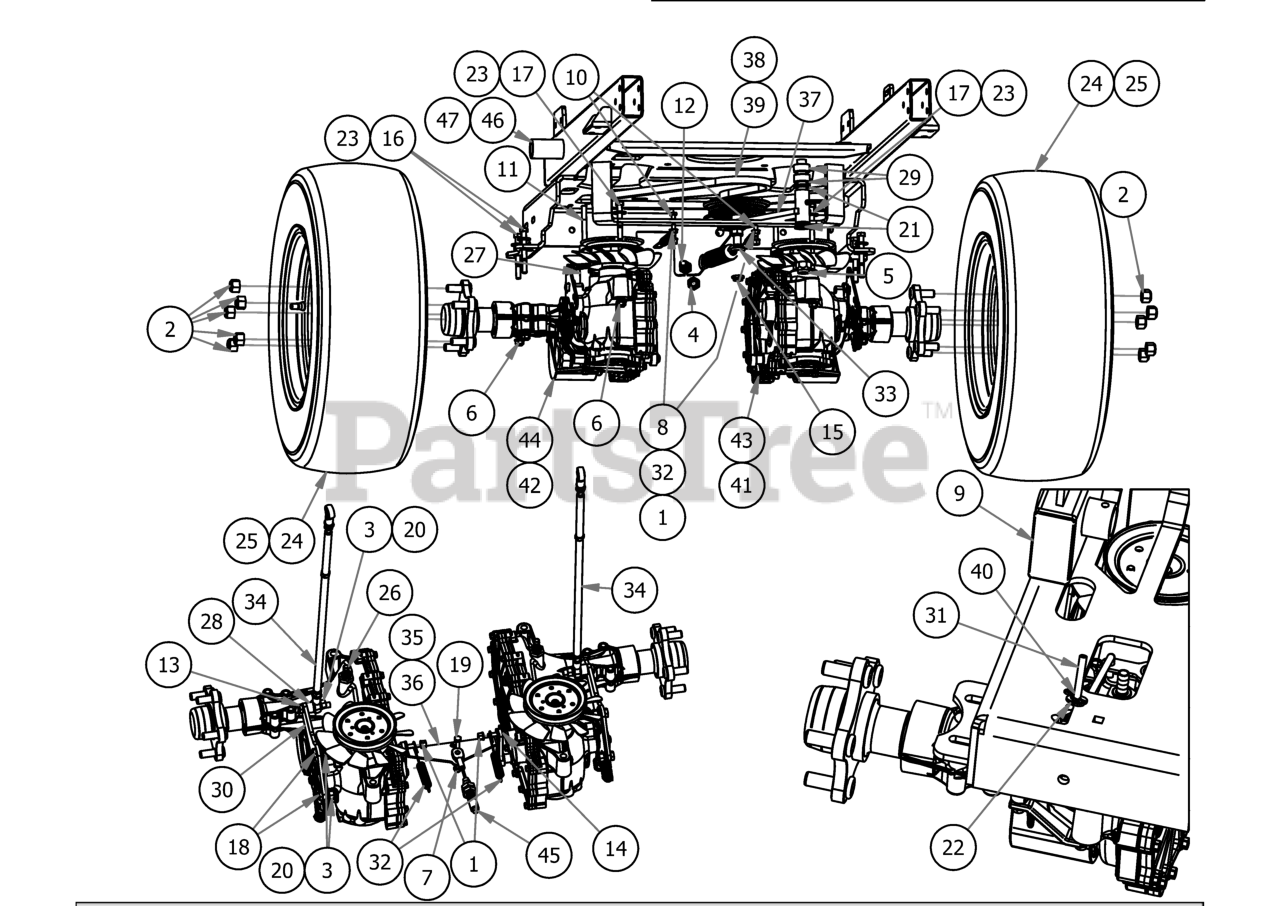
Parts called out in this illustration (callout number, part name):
1	1/4-20 Nylon Insert Flange Nut
2	Acorn Lug Nut
3	3/8" Hex Nut
4	1/2-13 Hex Nuts Zinc
5	5/8-11 NYLON INSERT LOCKNUT ZINC (NOT ON 36)
6	5/16-18 Nylon Flange Nut
7	1/4" Nylock Nut
8	1/4-20 Hex Flange Nuts Zinc w/Serrations
9	1 1/2 x 3 Frame Plug
10	1/4-20 x 2 Hex Bolt
11	5/16x6 Carriage Bolt-Grade 5
12	All Thread-Pump Idler Tensioner
13	3/8"-16 x 2" Gr 5 Hex Bolt
14	1/4-20 x 1 GR 5 hex bolt zinc
15	1/2-13 NYLON INSERT JAM LOCKNUT ZINC
16	5/16" x 3" Hex Bolt
17	5/16" x 2 1/2" Bolt
18	3/8-16 X 1 GR 5 Hex Bolts Zinc
19	1/4" x 3/4" Hex Bolt
20	3/8" Lock Washer
21	.630 ID Plastic Washer (NOT ON 36)
22	1/4 USS FLAT WASHER (3/4 OD) ZINC
23	5/16 USS FLAT WASHER (7/8 OD) ZINC
24	23x9-12 Reaper Turf Tire & Wheel Assembly
25	21/7x10 Reaper Tire-36 Revolt
26	45 degree fitting
27	2017 Transaxle Spacer
28	ACS Spacer 3/4x3/8x1/2
29	5/8" x 1/" Collar W/One Set Screw (NOT ON 36)
30	Stand On Control Arm Plate
31	2019 Stand On Neutral Rod
32	Brake Spring
33	Deck Idler Spring
34	2019 Stand On Drive Push Rod Assembly
35	2020 36 Brake Bracket
36	Brake Bracket
37	2019 Stand On Idler Assembly (NOT ON 36)
38	2019 Renegade Pump Belt (36" ONLY)
39	2019 Stand On Pump Belt (Timken# 47-2827)
41	Right ZT Transaxle
42	Left ZT Transaxle
43	Left 3400 IZT
44	Right 3400 IZT
45	Brake Cable
46	2019 Stand On Frame Weldment
47	2020 36 Stand On Frame Weldment
